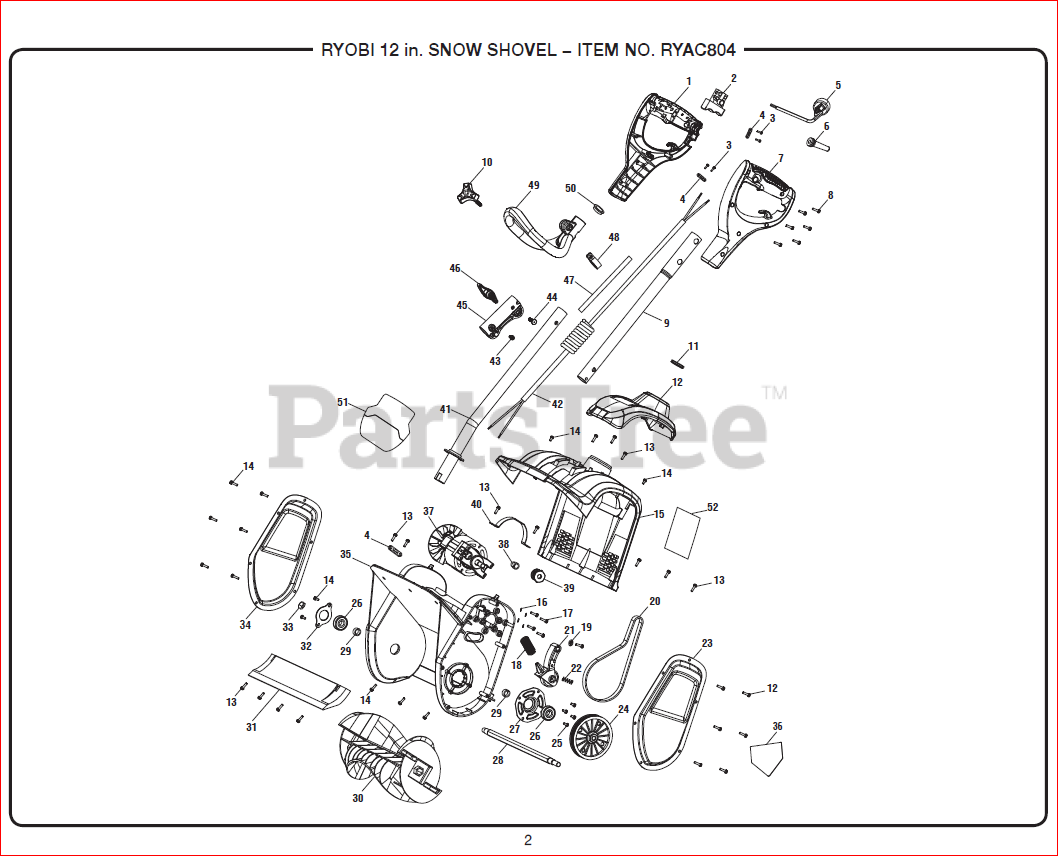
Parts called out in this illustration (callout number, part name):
1	Handle (Right)
3	Screw (M4 x 10 mm)
4	Strain Relief
5	Power Cord
7	Handle (Left)
8	Screw (M4 x 16 mm)
9	Upper Shaft
10	Knob Screw (Front Handle)
13	Screw (M4.2 x 16 mm)
14	Screw (M4.2 x 12 mm)
17	Screw (Pan Hd.)
18	Compression Spring
21	Idler Assembly
22	Compression Spring
23	Cover (Left)
24	Large Pulley Assembly w/Insert
25	Screw (M4.2 × 9.5 mm)
26	Ball Bearing (6201-2RS)
27	Bearing Plate (Left)
29	Sleeve Bearing
30	Auger (Impeller)
31	Scraper Blade
32	Bearing Plate (Right)
33	Lock Nut (M10)
34	Cover (Right)
35	Lower Housing.
36	Danger Label (No Hands/Feet)
37	Motor Assembly
38	Motor Pulley Spacer
39	Small Pulley
40	Motor Bracket
41	Lower Shaft
42	Coiled Wire Assembly
43	Screw (M5 x 9 mm, Pan Hd.)
46	Knob (Shaft)
49	Front Handle
51	Performance Label
52	Data Label
